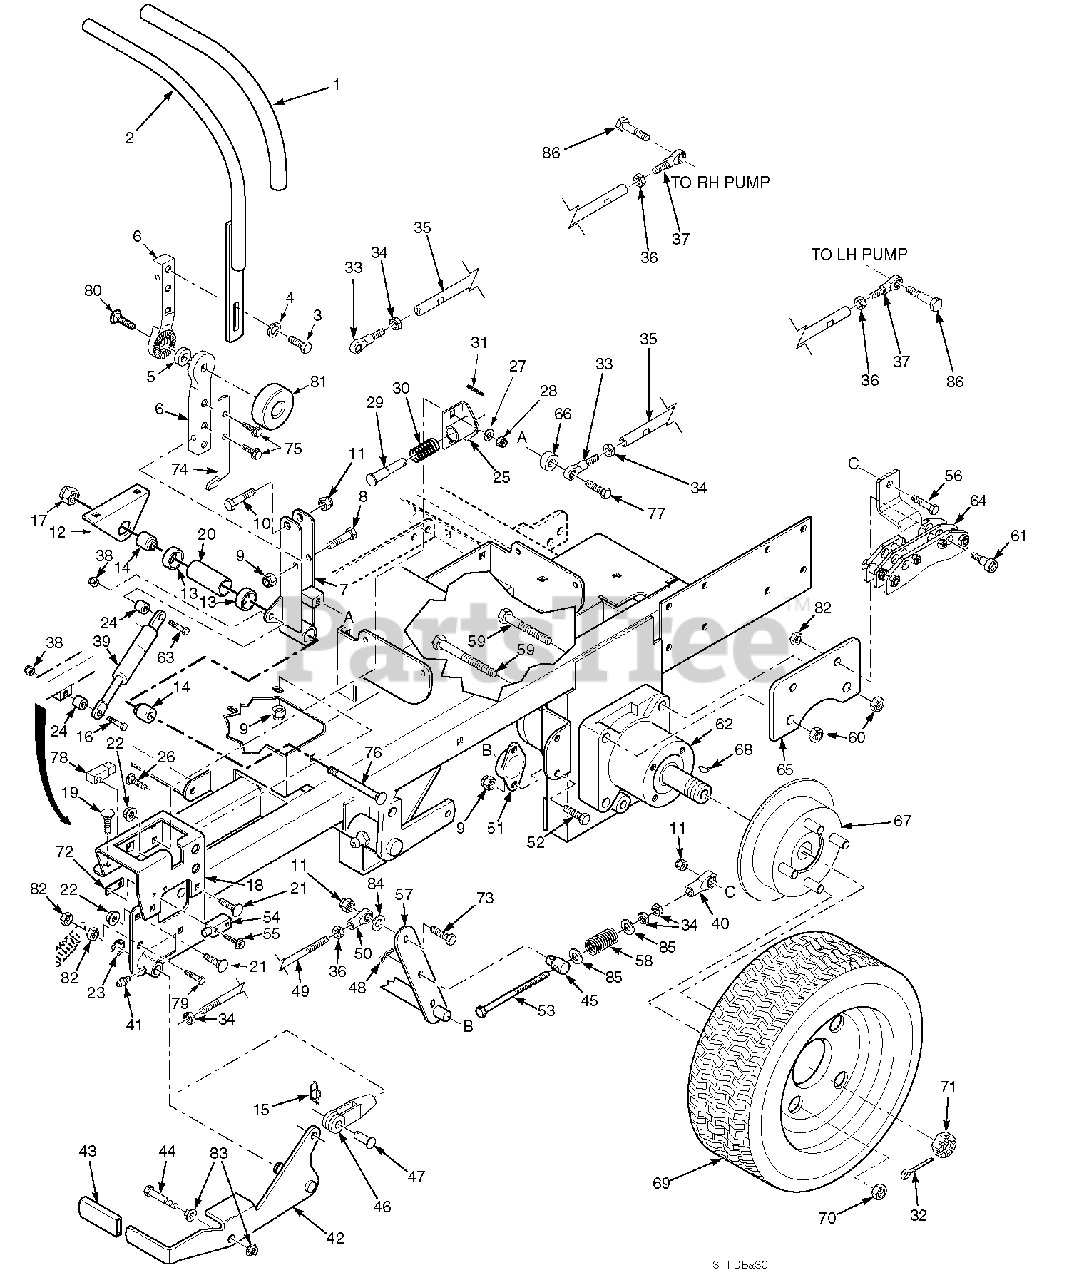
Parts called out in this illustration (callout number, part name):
1	Grip, Handle Bar
2	Handle Bar, LH
3	Bolt, Hex Head 5/16-18 x 1"
4	Lockwasher, 5/16"
5	Rubber Spacer
6	Bar, Control Lever
7	Control Lever Weldment, LH
8	Bolt, Hex Head 5/16-18 x 2"
9	Nut, Hex Elastic Stop 5/16-18
10	Bolt, Hex Head 3/8-16 x 2"
11	Nut, Hex Elastic Stop 3/8-16
12	Mount, Control Linkage
13	Ball Bearings, Neutral Return
14	Spacer
15	Pin, Rue Cotter 3/8 Dia.
16	Bolt, Hex Head, 5/16-18 x 2.75 Zinc
17	Nut, Hex Elastic Stop 5/8-11
18	Bracket, Control Lever LH
19	Bolt, Carriage 5/16-18 x 1"
20	Spacer, Bearing
21	Bolt, Carriage 5/16-18 x 3/4"
22	Nut, Hex Serrated Flange 5/16-18
23	Ring, Retaining 5/8" External "E"
24	Spacer
25	Bracket, Neutral Return
26	Bolt, Carriage 1/4-20 x 3/4"
27	Flatwasher, 1/4" (.312 x .750 x .065)
28	Nut, Hex Elastic Stop 1/4-20
29	Pin, Retaining Spring
30	Spring
31	Roll Pin, Spring 5/32 x 3/4"
32	Pin, Cotter 9/16 x 1-1/2"
33	Rod End, Male 3/8-24 RH Thread
34	Nut, 3/8-24 RH Thread
35	Tube, Control Link
36	Nut, Hex 3/8-24 LH Thread
37	Rod End, Male 3/8-24 LH Thread
38	Locknut, 5/16-18, Elastic Stop
39	Gas Damper
40	Rod End, 3/8-24 RH Female
41	Grease Fitting
42	Lever, Parking Brake
43	Grip, Parking Brake
44	Bolt, Hex Head 3/8-16 x 2-3/4"
45	Swivel Joint
46	Clevis, Traction Control
47	Pin, Clevis
48	Hair Pin Cotter
49	Rod, Parking Brake
50	Rod End, LH Thread
51	Bushing, Self Align
52	Bolt, Hex Head 5/16-18 x 3/4"
53	Bolt, Hex Hd 3/8-24 x 5-1/2"
54	Switch, Parking Brake
55	Screw, Hex Slotted Washer Head #10 32 x 3/4"
56	Bolt, Hex Head 3/8-16 x 1-1/4"
57	Bellcrank, Brake Actuator
58	Spring
59	Bolt, Hex Hd 1/2-13 x 2-3/4"
60	Locknut, Hex 1/2-13 Center Lock
61	Bolt, Shoulder 1/2 x 3/8-16 x 2-3/4"
62	Wheel Motor, Parker
63	Bolt, Hex Head, 5/16-18 x 1.75, Zinc
64	Brake Caliper
65	Mounting Bracket, Brake
66	Spacer
67	Wheel Hub/Disk Brake Assembly
68	Key, Woodruff 5/16 x 1"
69	Wheel Assembly 24 x 12-12 Turf Master
70	Lug Nut, 1/2-20
71	Nut, Hex Castle
72	Threaded Plate
73	Bolt, Hex Head 3/8-16 x 1-1/2"
74	Actuator, Switch
75	Bolt, Hex Serrtd Flng 5/16-18 x 3/4"
76	Bolt, Hex Head 5/8-11 x 4-1/2"
77	Bolt, Hex Head 3/8-16 x 1-1/4"
78	Switch, Handle Neutral
79	Bolt, Hex Head 3/8-16 x 1-1/4" Grd 8
80	Bolt, Carriage 3/8-16 x 1-1/2"
82	Nut, Center Lock 3/8-16
83	Nut, Serrated Flange 3/8-16
84	Flatwasher, 3/8-.391 x .938 x .105
85	Flatwasher, 3/8-.406 x .812 x .065
86	Bolt, Hex Head, 3/8-16 x 1-3/4"
